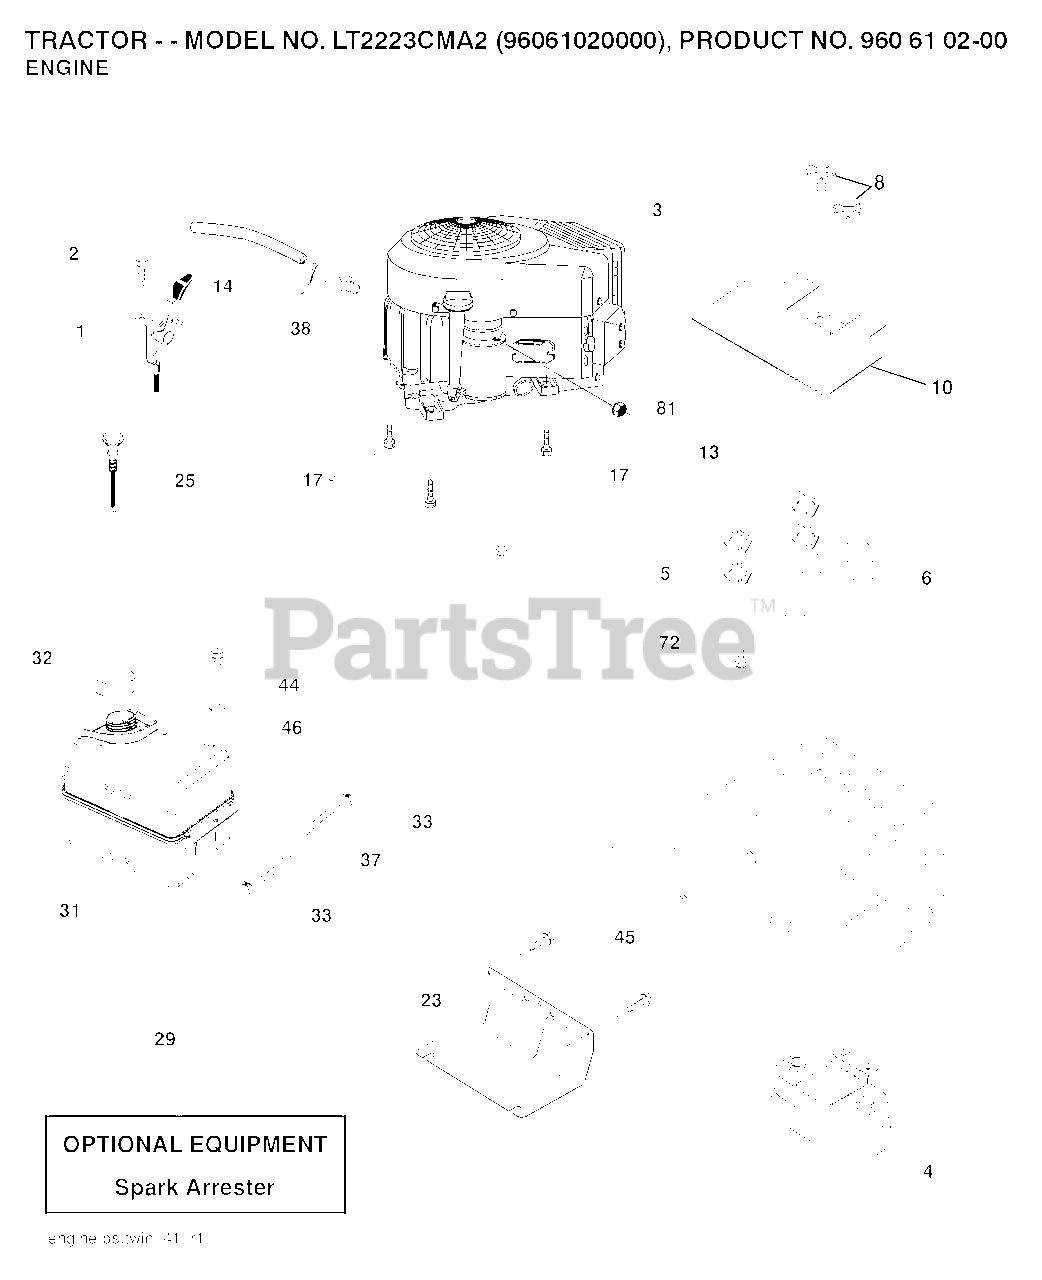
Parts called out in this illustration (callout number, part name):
1	THROTTLE CABLE
2	SCREW
4	MUFFLER.TWIN.CYL.LOW.TONE
5	EXHAUST TUBE RH
6	TUBE MANIFOLD LH
8	BOLT, 5/16-18 X 1 3/4
10	RP SHIELD HEAT MUFFLER
13	GASKET.MUFFLER
14	TUBE, DRAIN OIL ASM.
17	SCREW.3/8-16
23	SHEILD.BROWNING.DBR.GUARD
25	CONTROL CHOKE
29	ARRESTER SPARK (OPTIONAL)
31	FUEL TANK FRT 2 GAL.
32	FUEL CAP
33	HOSE CLAMP
37	LINE.FUEL.20
38	PLUG DRAIN OIL EASY
44	SCREW HEXWSHR 1/4-20X3/4
45	SCREW, 3/8-16X3/4
72	SCREW.SOCKET.HEAD.5/16-18
81	NUT
